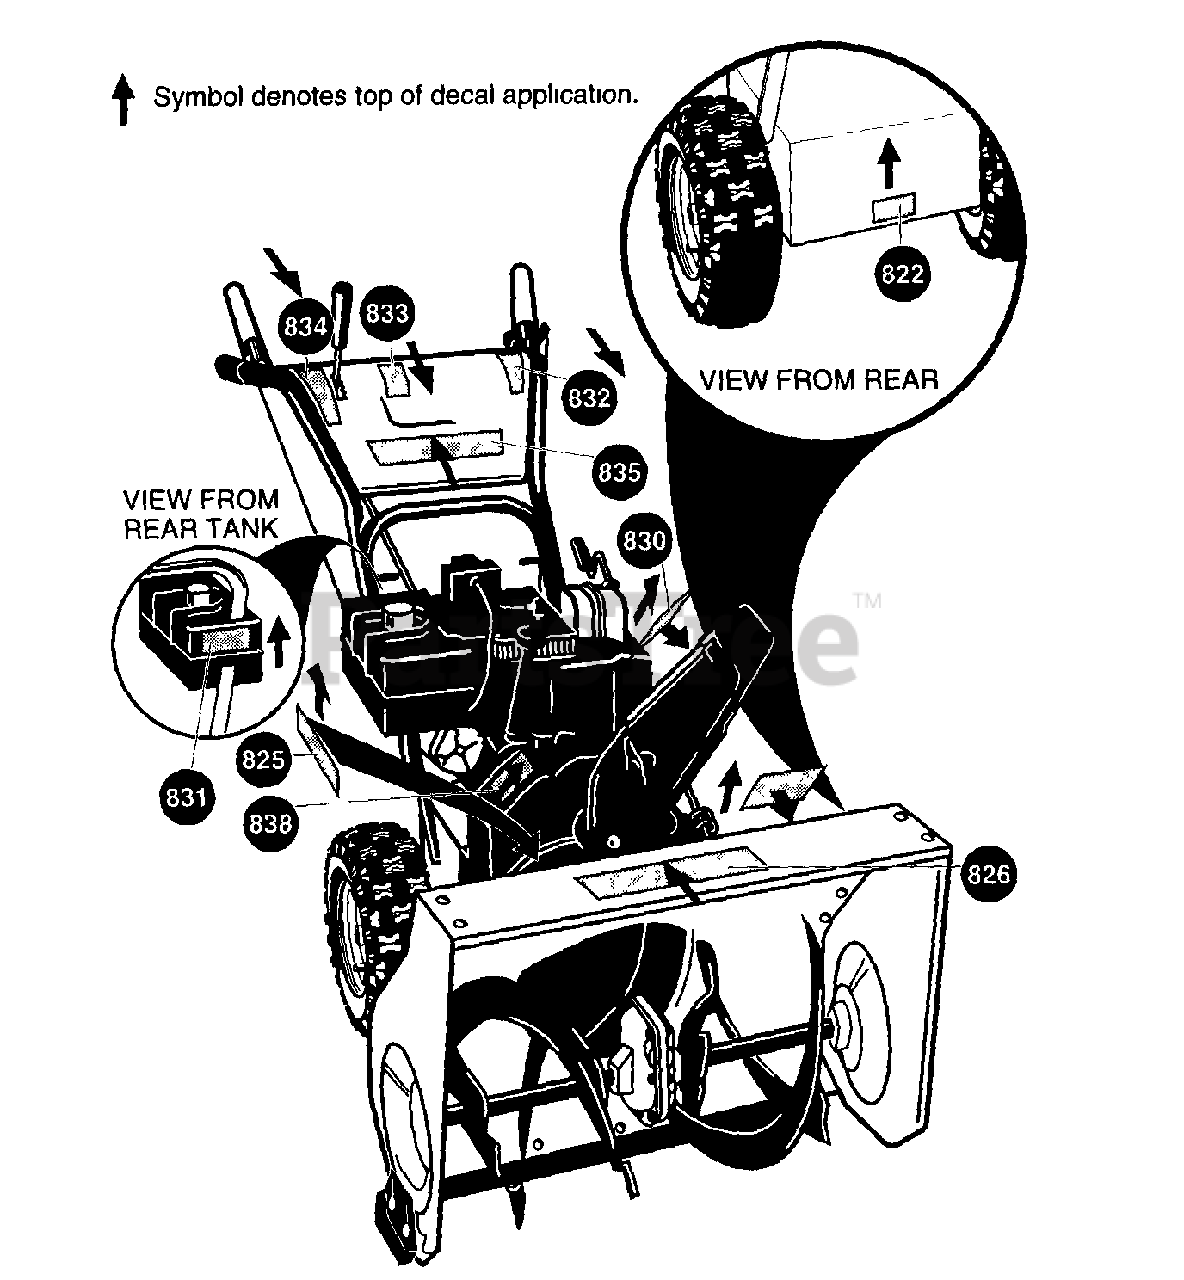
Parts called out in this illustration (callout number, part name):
822	DECAL, OVER ADJ OF DISC
824	DECAL, DANGER FOOT
825	DECAL, DUAL STAGE
826	DECAL, HUSQ ST927E
830	DECAL, DANGER FINGER
832	DECAL, TRACTION DRIVE
833	DECAL, SNOW CONDITIONS
834	DECAL, AUGER DRIVE
835	DECAL, CONTROL PANEL
838	DECAL, BELT ADJ
